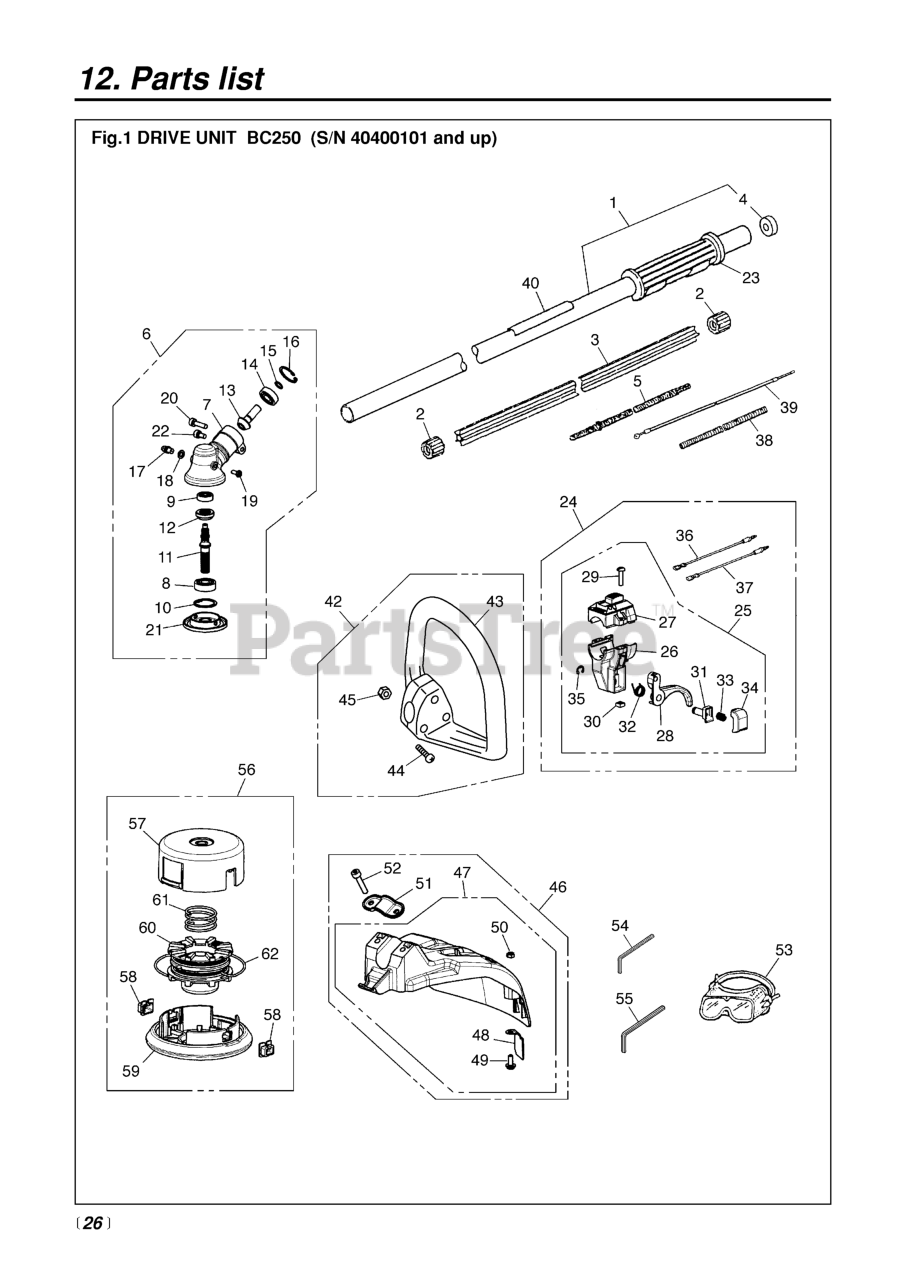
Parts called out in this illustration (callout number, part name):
1	PIPE
4	SEAL
5	SHAFT
6	GEARCASE ASSY.
7	GEARCASE
8	BEARING
9	BEARING (RPLS T3300-13521)
10	RING, SNAP, M26 X 1.2
11	SHAFT
12	GEAR
13	PINION
14	BEARING (RPLS T3300-13531)
15	RING, SNAP (RPLS T3300-13330)
16	RING, SNAP, M24 x 1.2
17	FITTING, GREASE
18	WASHER, M6 X .8
20	BOLT (RPLS 2850-14220)
21	HOLDER (A)
22	BOLT
23	GRIP (RPLS 3577-32140 & 3220-
24	LEVER COMP.
25	LEVER (USE 848-8R2-0313)
27	COVER (USE 848-8RA-0340)
28	FLEX, TRIGGER
36	CORD (A), BLACK
37	CORD (B), RED
39	CABLE COMP (RPLS 1633-83100)
40	PLATE, NAME
42	HANDLE ASSY.
44	SCREW, M5 x 30
45	NUT, M5 X 4
46	GUARD ASSY. (RPLS -24002)
47	GUARD COMP.
48	BLADE (RPLS T3002-24120)
49	SCREW TORX
50	NUT
51	CLAMP (REPLACES 5807-24120)
52	BOLT, M6 x 1.30
53	GOGGLE
54	WRENCH (T20)
55	WRENCH(T25)
56	TAP HEAD COMP.
57	CASE (REPLACES -15111)
58	EYELET
59	COVER (REPLACES -15131)
60	HOLDER, CORD (REPLACES-15141)
61	SPRING
62	CORD
